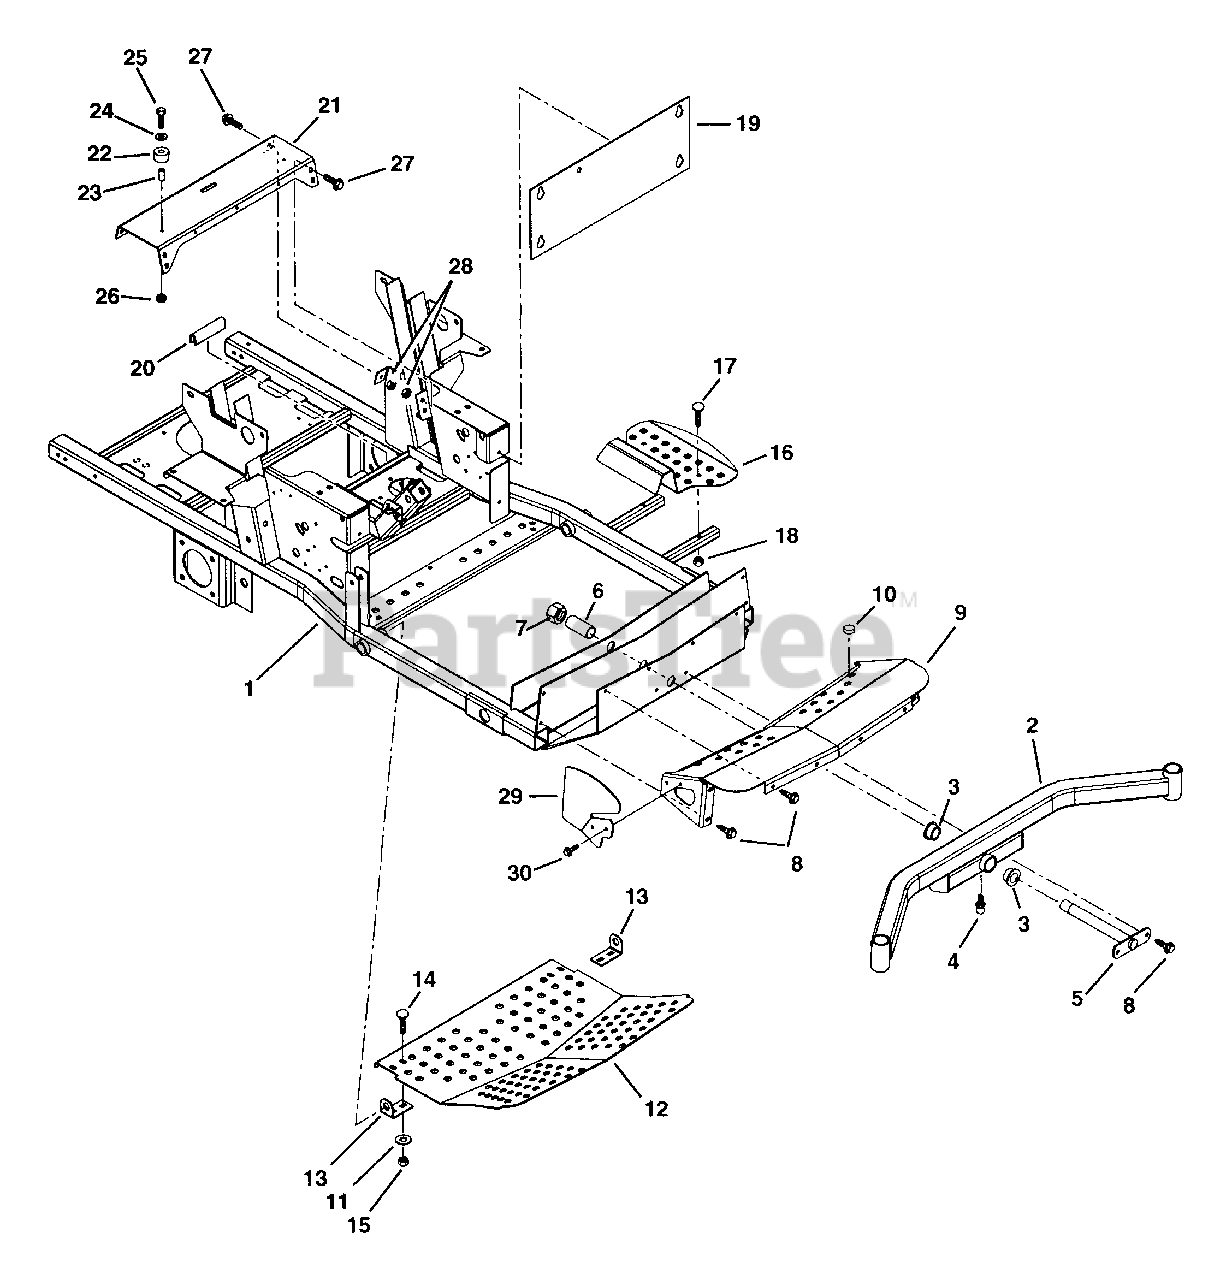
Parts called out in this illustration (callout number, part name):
1	Frame
2	Axle-Front
3	Bushing-Flange 1.020 x 1.385 x .75 x 1.75
4	Fitting-Lube .25-28 x .256
5	Pin-Axle
7	Nut-Locking 1.0-14
8	Screw-Tapping .38-16 x .75
9	Cover-Axle
10	Button Bumper
11	Washer-Flat-Steel .38 x .875 x .083
12	Panel-Inspection
13	Mount-Inspection Panel
14	Bolt-Round Head Square Neck .38-16 x 1.00 Grade 5
15	Nut-Locking-Nylon .38-16
16	Step-Ingress
17	Bolt-Round Head Square Neck .31-18 x 1.75 Grade 5
18	Nut-Locking-Nylon .31-18
19	Plate-Kick
20	Strip-Cowl
21	Channel-Cross
22	Bumper-Seat
23	Bushing-Sleeve Steel .265 x .375 x .250
24	Washer-Flat-Steel .312 x. 734 x .065
25	Bolt-Hex .25-20 x .75 Grade 5
26	Nut-Locking-Center .25-20
27	Bolt-Serrated Flange Washer Head .38-16 x 1.00
28	Nut-Retainer .375-16 x .37
29	Cover, Cylinder Rod End
30	Screw-Tapping .25-20 x .50 Hex Washer Head
